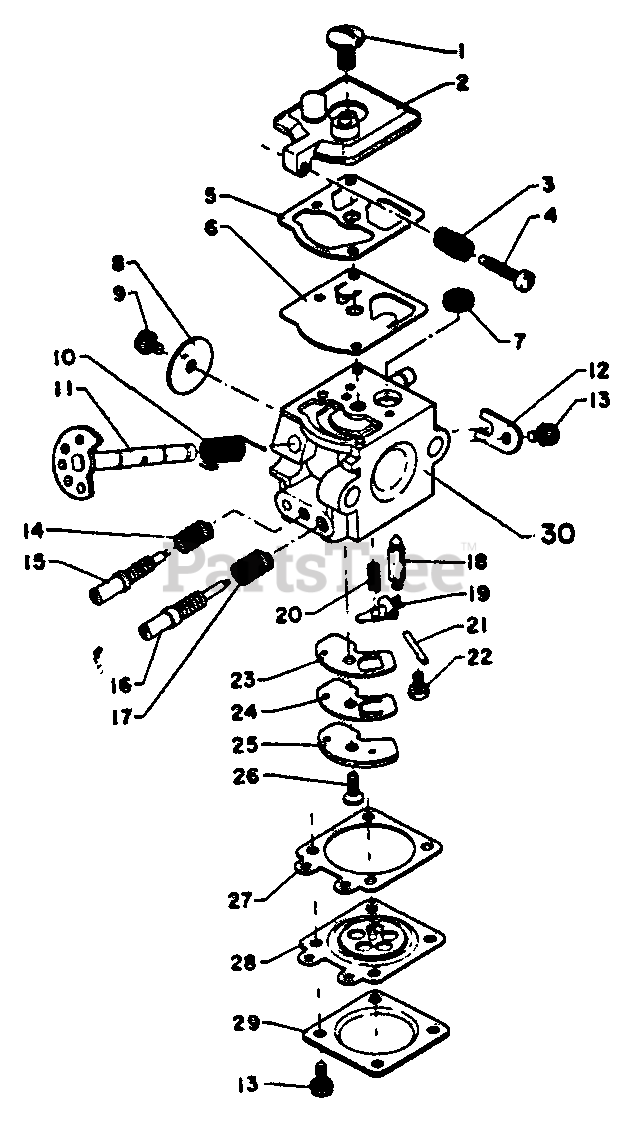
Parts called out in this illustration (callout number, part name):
2	COVER, PUMP
3	SPRING, IDLE ADJUST
4	SCREW, IDLE ADJUST
5	GASKET, FUEL PUMP
6	DIAPHRAGM, FUEL PUMP
7	STRAINER
8	VALVE, THROTTLE
10	SPRING, THROTTLE RETURN
11	SHAFT, THROTTLE
12	CLIP, THROTTLE SHAFT
14	SPRING, NEEDLE
15	NEEDLE, IDLE
16	NEEDLE, HIGH SPEED
17	SPRING, NEEDLE
18	VALVE, INLET NEEDLE
19	LEVER, METERING
21	PIN, METERING LEVER
22	SCREW, METERING LEVER PIN
23	GASKET, CIRCUIT PLATE
24	VALVE, CHECK
25	PLATE, CIRCUIT
26	SCREW, CIRCUIT PLATE
27	GASKET, METERING DIAPHRAGM
28	DIAPHRAGM, METERING
29	COVER, METERING DIAPHRAGM
30	BODY, CARBURETOR
